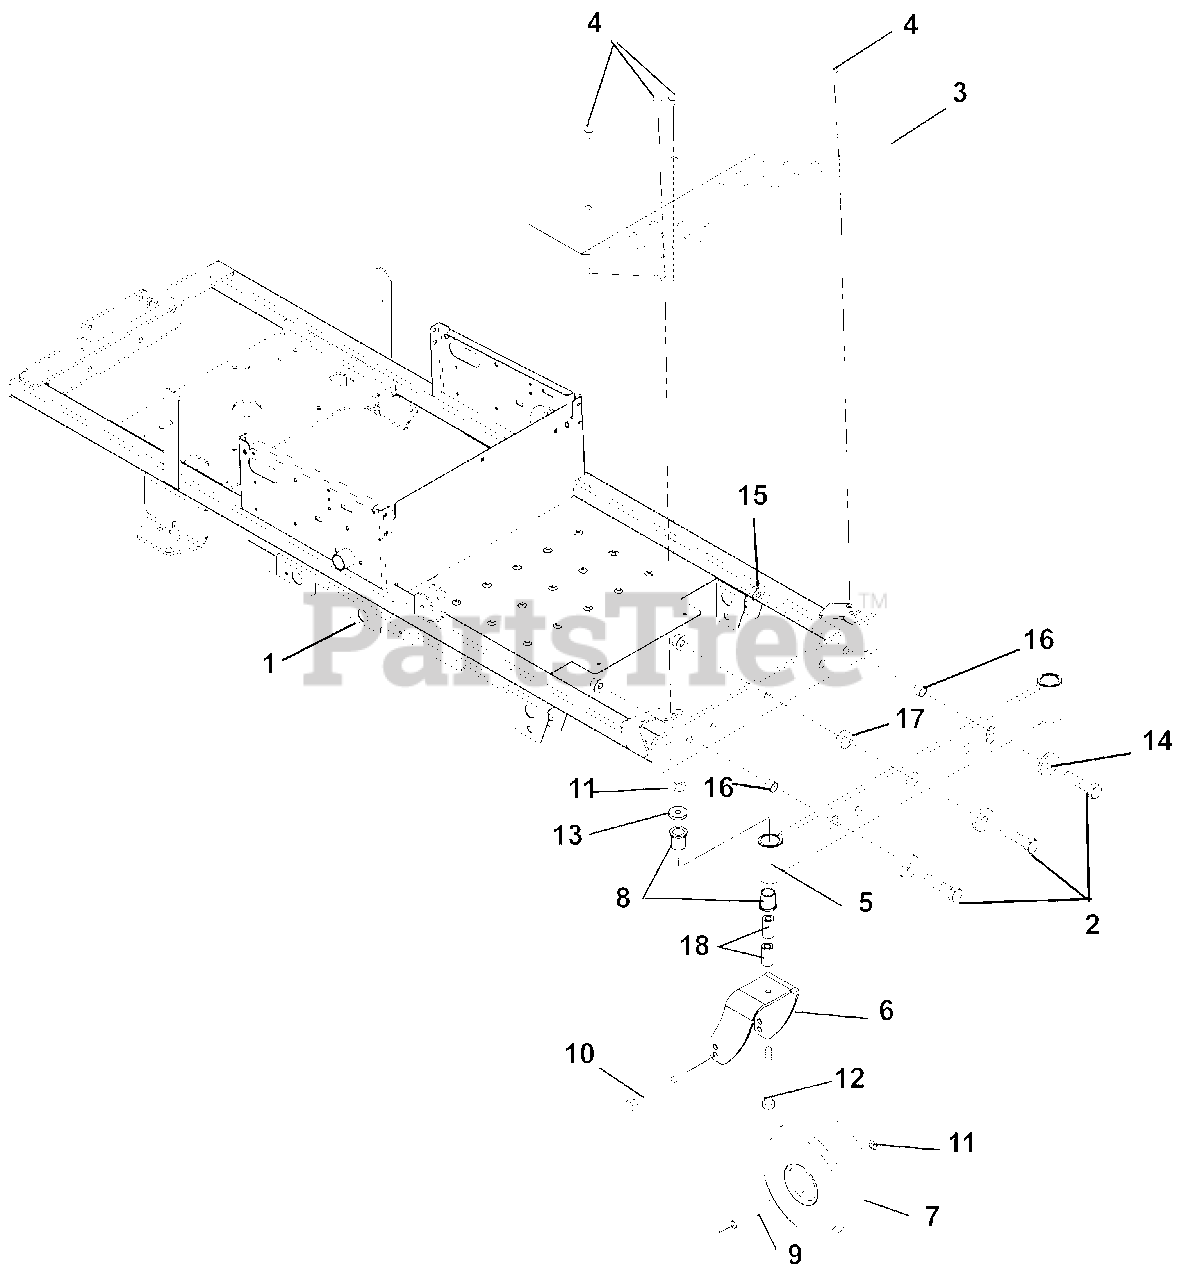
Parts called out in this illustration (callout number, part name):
1	Weldment, Frame
2	Bolt, Hex .62-11 x 2.25 Grade 8
3	Footrest, MZ
4	Screw, Tapping .31-18 x .50
5	Weldment, Front Axle
6	Fork, Caster
7	Wheel/Tire Assembly, 11.0 x 4.0 x 5.0, Monitor
8	Bushing, Flange 1.00 x 1.25 x 1.50 x 1.50
9	Spacer, Wheel
10	Bolt, Hex .50-13 x 6.50 Grade 5
11	Nut, .50-13 Nyloc Flange
12	Bolt, Hex .50-13 x 5.00 Grade 5
13	Washer, Flat Steel .511 x 1.441 x .125
14	Washer, Flat .640 x 1.81 x .250
15	Nut, Nyloc Flange .62-11
16	Spacer, .750 D x .558 Long
17	Bushing, Axle Pivot
18	Spacer, Caster Fork
